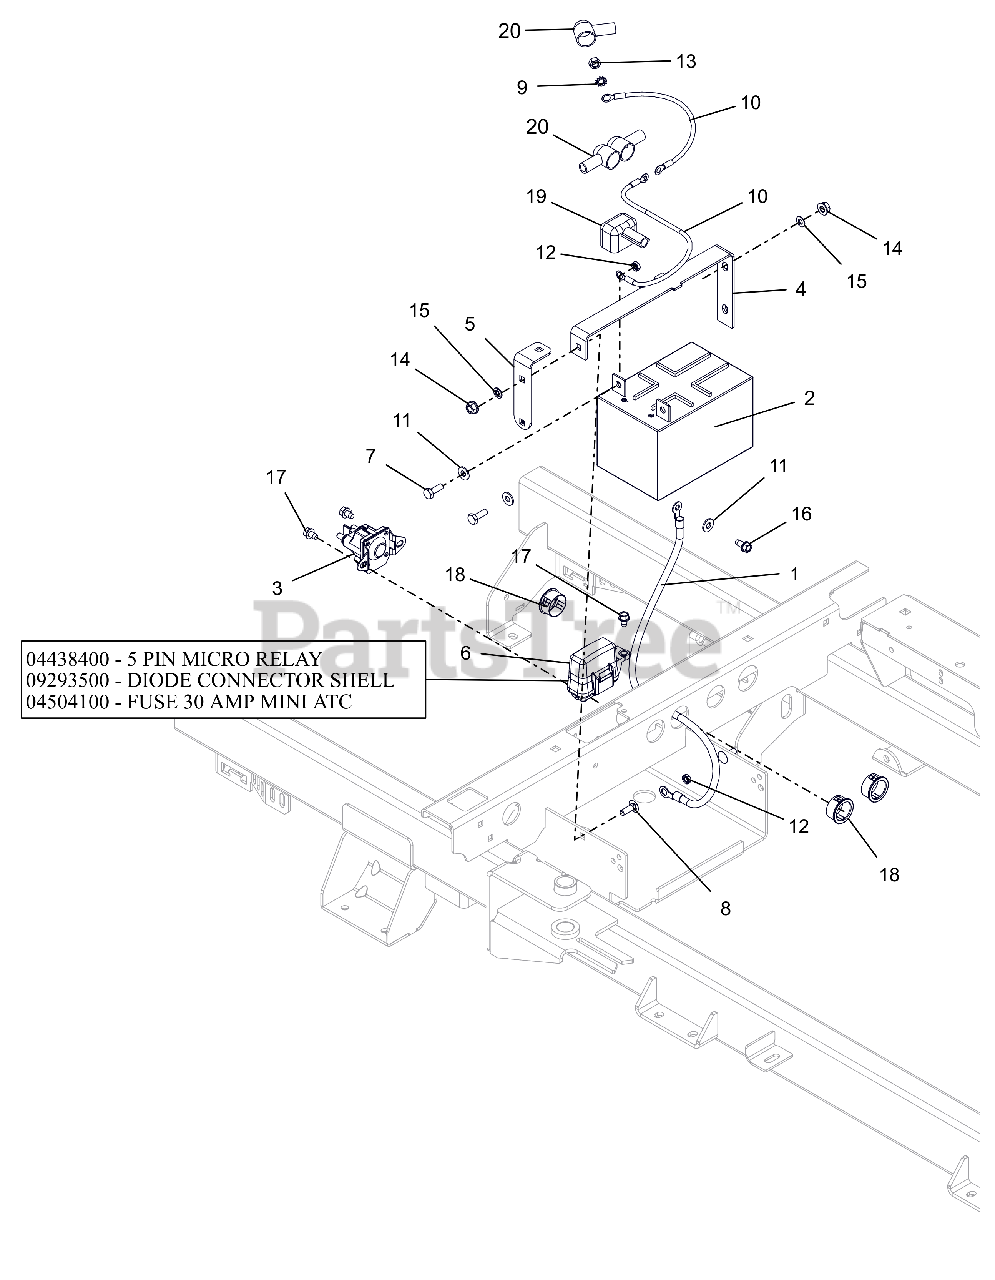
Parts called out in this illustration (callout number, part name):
1	CABLE-NEGATIVE BATTERY 24.00"
2	BATTERY, 12V 12A-190CCA
3	SOLENOID, STARTER (SEALED)
4	BRKT, BATTERY HOLD-DOWN
5	BRKT, BATTERY HOLD DOWN
6	HARNESS, WIRE-4POS KEY IKON/ZT
6	RELAY,MICRO5 TERML W/RESISTOR
6	DIODE, CONNECTOR SHELL
6	FUSE,30 AMP MINI-ATC
7	@BLT-HEX .25-20X.75 GR5 YWZC
8	@BLT-RDHDSQNK .25-20X.75 G5YZ
9	@WSHR-LK-EXT.262X.502X.026YWZC
10	CABLE,POS W/2 1/4 RING 15.0 LG
11	@WSHR-FL-STL.281X.62X.065 YWZC
12	NUT, 10-24 KEPS
13	@NUT-HEX .25-20 YWZC
14	@NUT-LK-TOP-FLG .25-20 YWZC
15	NUT-PUSH .25X.50 O.D.
16	SCR-TAP .25-20X.50 HWH TR YWZ
17	@SCR-TAP .25-20X.37 HWH YWZ TR
18	BSHG, PANEL SNAP .937X1.11X.56
19	INSULATOR
20	BOOT, EYELET TERMINAL
